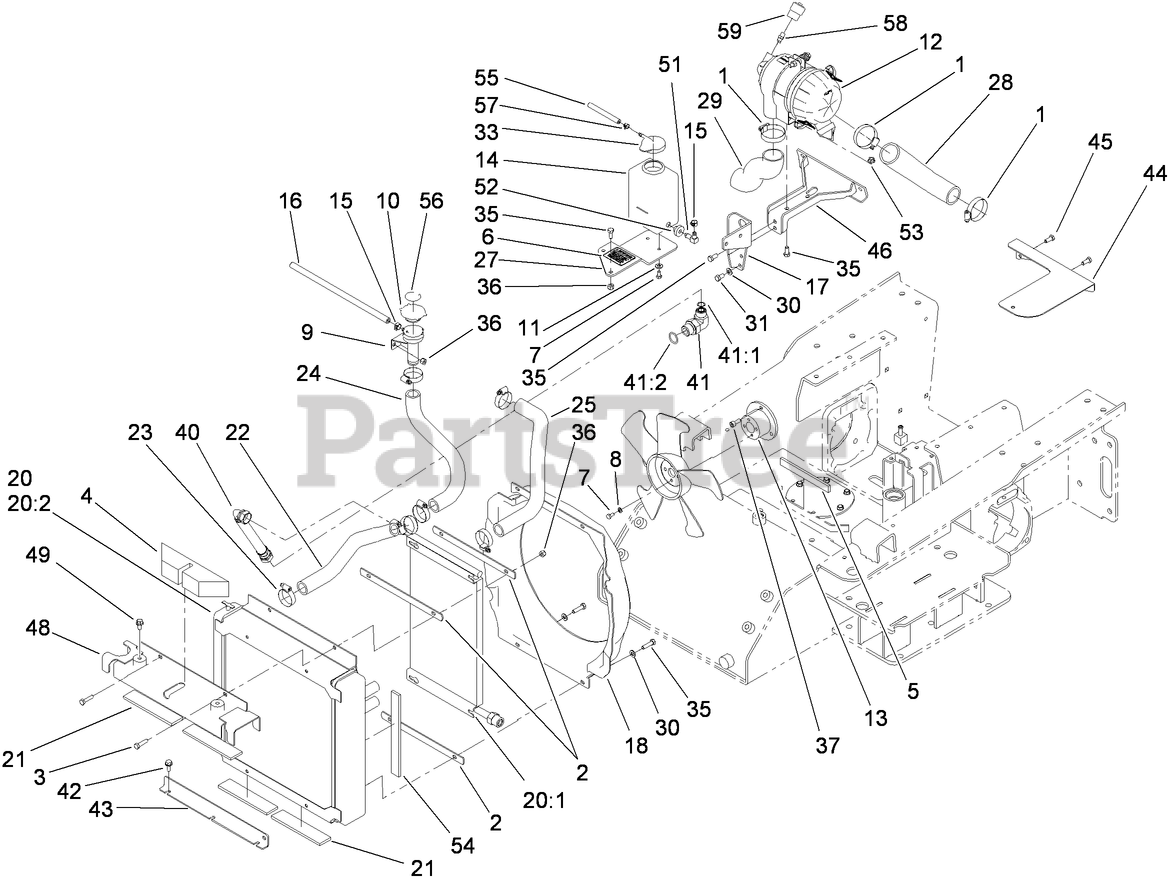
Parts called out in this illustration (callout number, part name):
1	CLAMP-HOSE
2	PLATE-BACKING
3	SCREW-HH
4	SEAL-FOAM
5	PAD-RUBBER
6	DECAL-RADIATOR FILL
7	SCREW-HH
8	WASHER-LOCK
9	TUBE-FILLER, RADIATOR
10	CAP-RADIATOR
11	WASHER-FLAT
12	AIR CLEANER ASM
13	SPACER-MACHINED
14	TANK-OVERFLOW
15	CLAMP-HOSE
16	HOSE-LP
17	MOUNT-FILTER, AIR
18	SHROUD-FAN
20	RADIATOR AND OIL COOLER ASM
20:1	COOLER-OIL, HYD
20:2	RADIATOR
21	PAD-RUBBER
22	HOSE-RADIATOR
23	CLAMP-HOSE
24	HOSE-RADIATOR
25	HOSE-RADIATOR
27	BRACKET-TANK, OVERFLOW
28	HOSE-AIR, INLET
29	HOSE-AIR
30	WASHER-PLAIN
31	BOLT
33	CAP-TANK, OVERFLOW
35	SCREW-HH
36	NUT-LOCK, NI
37	SCREW-CAP, HSH
40	HYD HOSE ASM
41	FITTING-ELBOW 90
41:1	O-RING
41:2	O-RING
42	SCREW-HWHTF
43	MOUNT-RADIATOR
44	PLATE-BAFFLE, STARTER
45	SCREW-HH
46	BRACKET ASM
48	BRACKET-RADIATOR
49	SCREW-HHF
51	FITTING-ELBOW-90
52	BUSHING
53	NUT-HF
54	FOAM-SEAL
55	HOSE-LP
56	DECAL-CAP, RADIATOR
57	CLAMP-HOSE
58	Nipple-Pipe
59	INDICATOR-MINI
